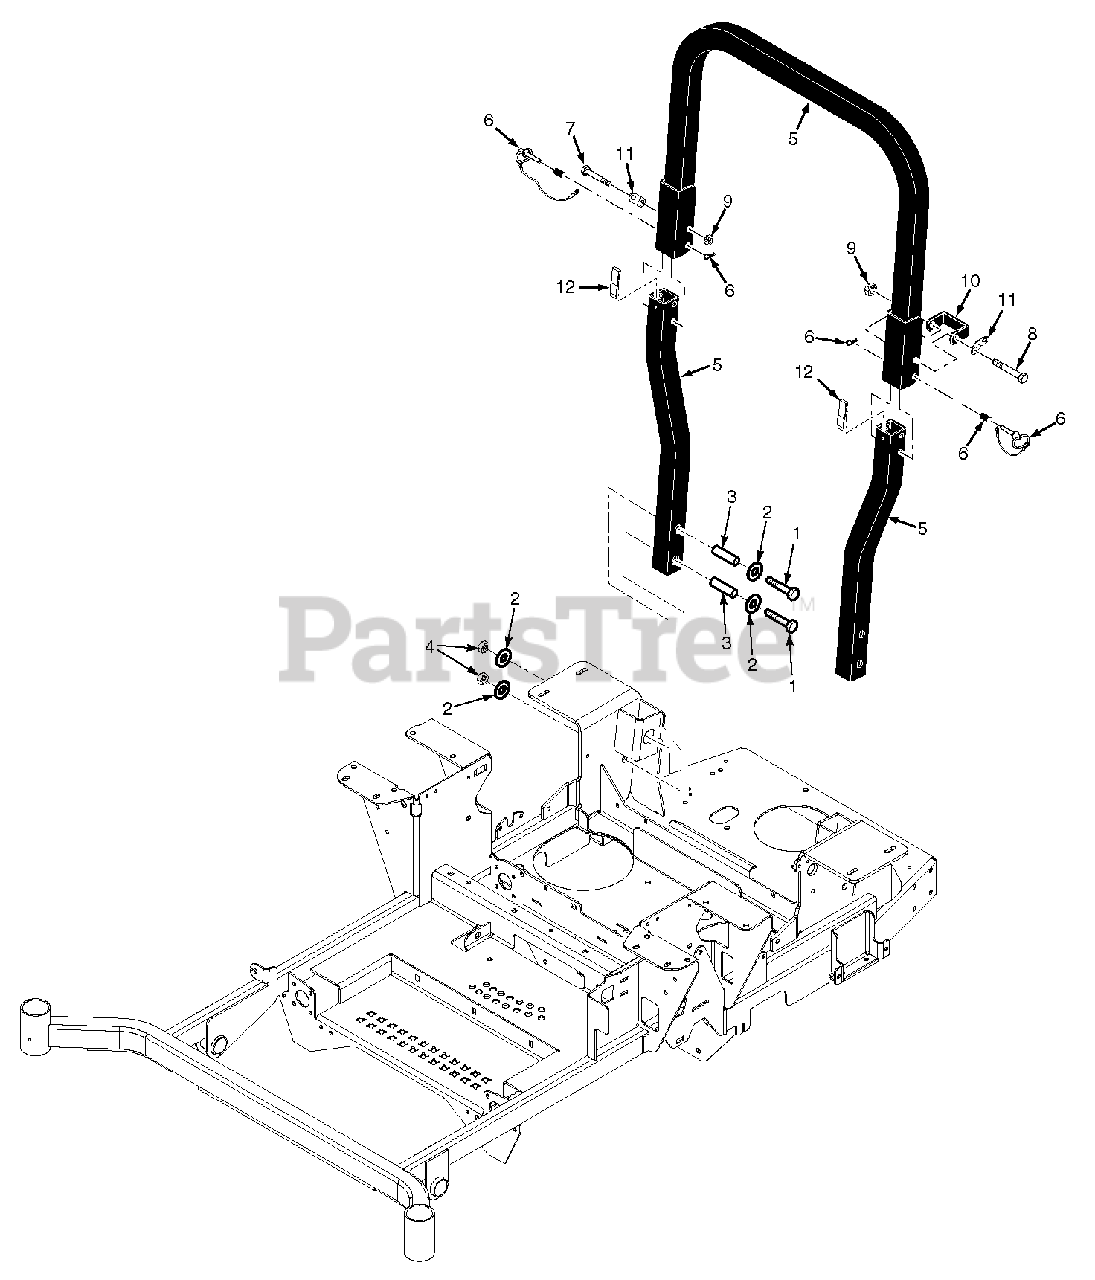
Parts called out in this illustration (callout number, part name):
1	Bolt, Hex Head 1/213 x 3" Gr. 8
2	Flatwasher, 1/2 - .531 x 1.062 x .095
3	Bushing, SFZ ROPS
4	Nut, Center Lock 1/2-13
5	ROPS
6	Pin Assembly, ROPS Hinge
7	Bolt, Hex Head 1/2-13 x 3-1/4"
8	Bolt, Hex Head 1/2-13 x 3-1/2"
9	Nut, 1/2-13 Center Lock
10	Stop, ROPS
11	Clip, ROPS
12	Spring, ROPS
